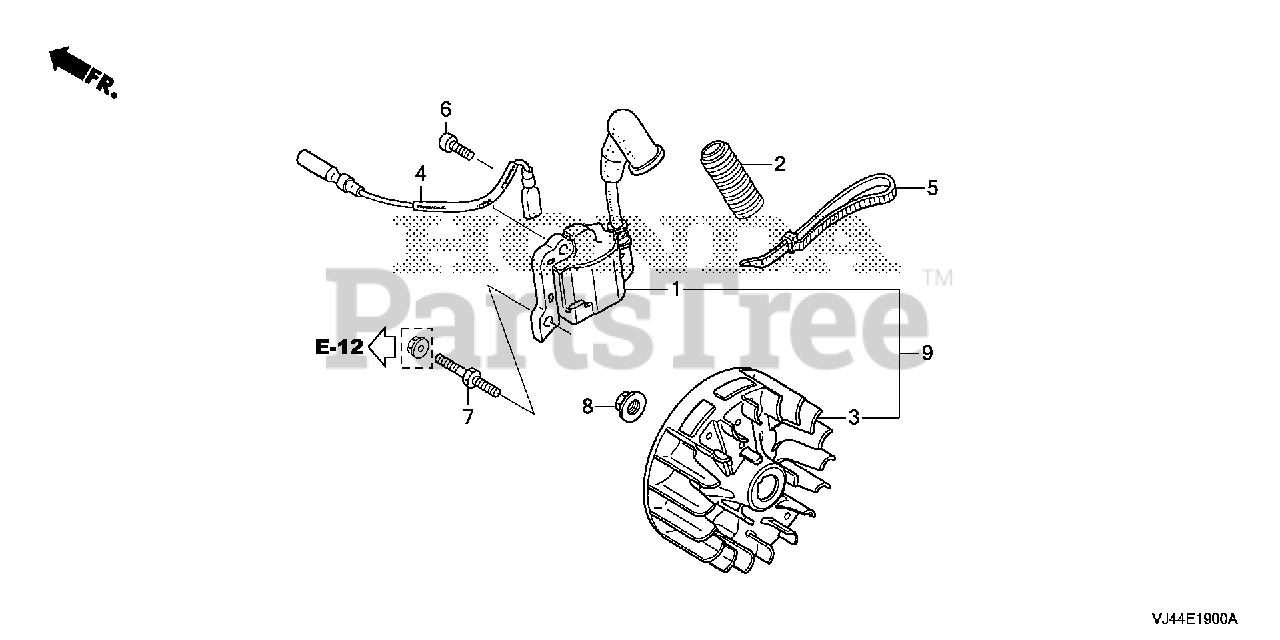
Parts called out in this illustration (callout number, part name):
1	COIL ASSY., IGNITION
3	FLYWHEEL
4	WIRE, STOP SWITCH
6	BOLT, SOCKET (4X14)
7	BOLT, SPECIAL STUD (4MM)
8	NUT, FLANGE (7MM)
9	IGNITION COIL & FLYWHEEL KIT
